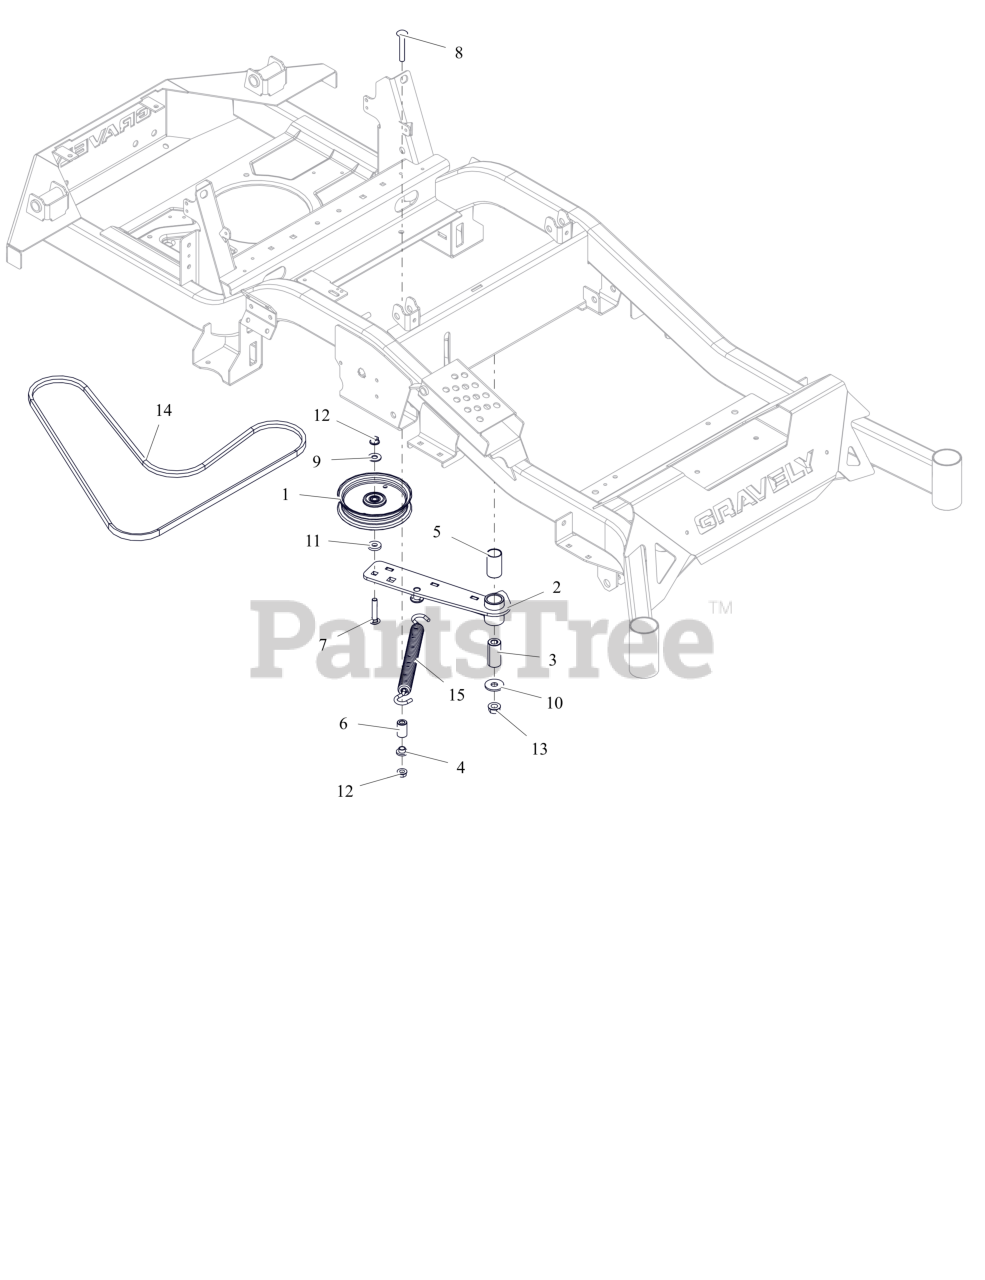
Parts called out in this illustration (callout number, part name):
1	IDLER- FLAT - 5.00" X .75"
2	WLDMT, HYDRO DRIVE IDLER ARM (BLACK)
3	BSHG, SPCR .502X.997X2.03 PM
4	BSHG-FLG .385X.500X.875X.406
5	BSHG, 1.00X1.125X1.937
6	BUSHING, SLV .380X.750X1.190
7	BLT, RHSN .38-16X2.00 G5 ZCC
8	BLT, RHSSN.38-16X2.50 G5 ZCC
9	WSHR,FLT .438X1.00X.083 ZCC
10	WSHR-FL-STL.511X1.44X.125ZC120
11	WSHR, FLT .406X1.00X.188 ZCC
12	NUT-LK-TOP-FLG .38-16 ZC120
13	NUT-LK-TOP-FLG .500-13 GF ZCC
14	V-BELT, 4L-WRAPPED
15	SPRING, EXTENSION
